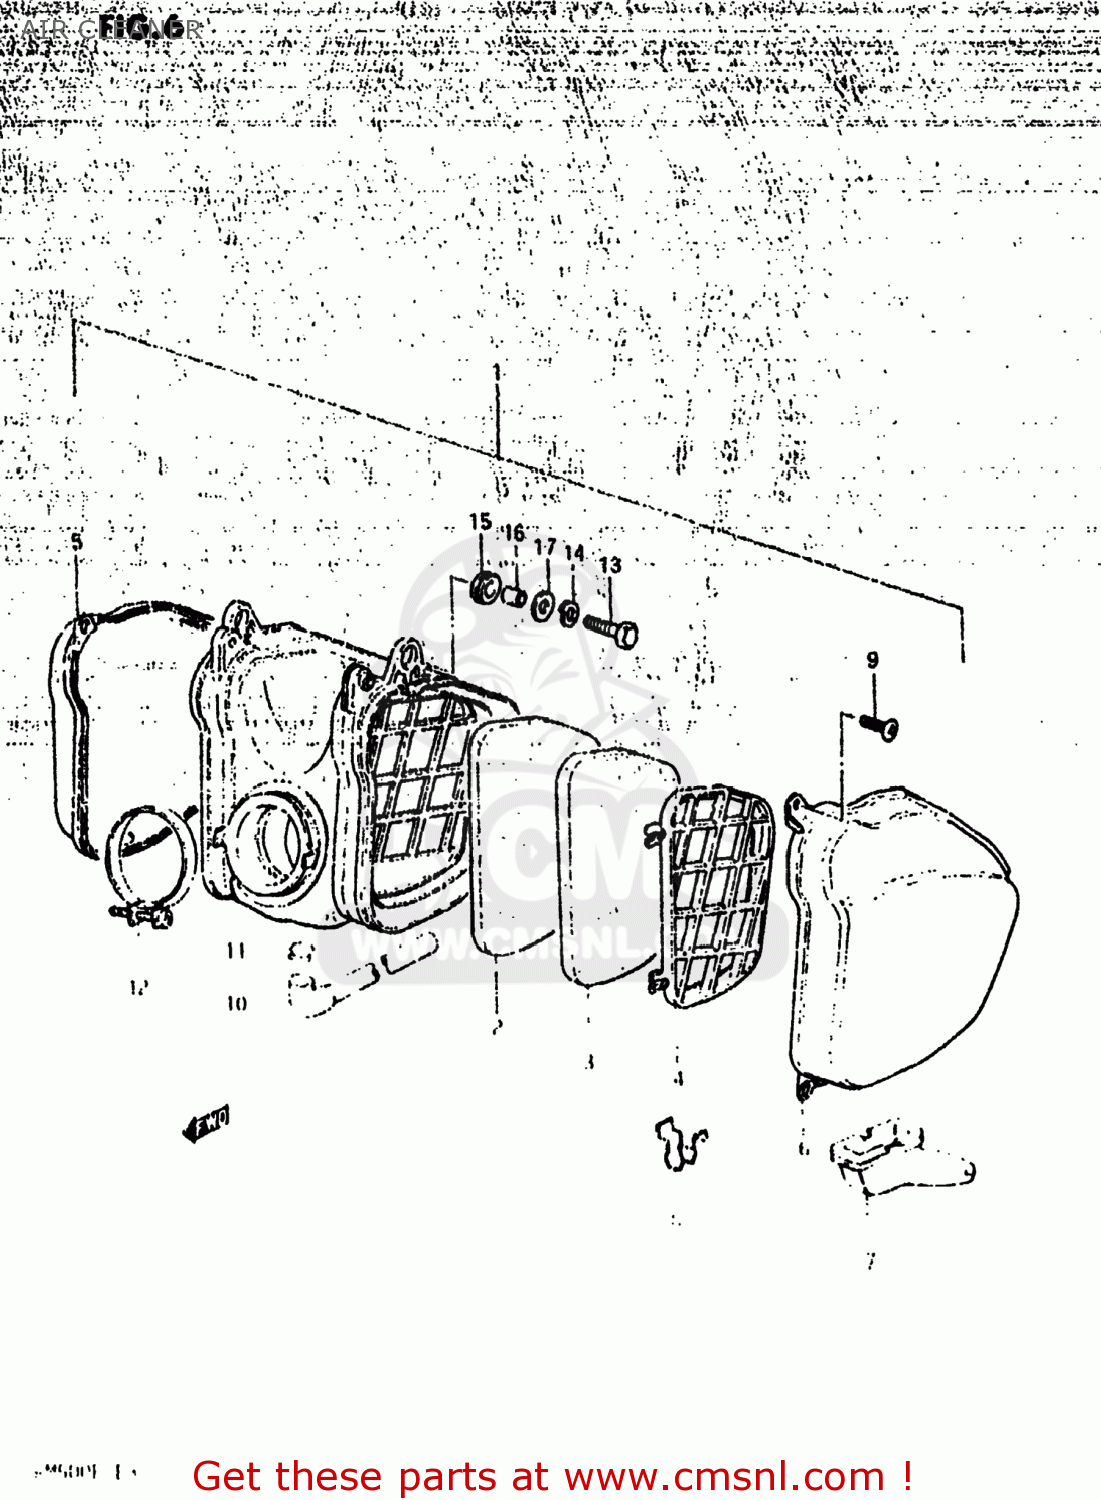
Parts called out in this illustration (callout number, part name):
1	CLEANER ASSEMBLY,AIR
2	FILTER
3	FILTER,2ND
4	HOLDER,AIR CLEANER,LEFT
5	CAP,AIR CLEANER,RIGHT
6	CAP,AIR CLEANER,LEFT
7	DRAIN TUBE
8	DRAIN STOPPER
9	SCREW
10	DRAIN TUBE
11	CLIP
12	CLAMP
13	BOLT
14	LOCK WASHER
15	CUSHION
16	SPACER (7X9X7)
17	WASHER
